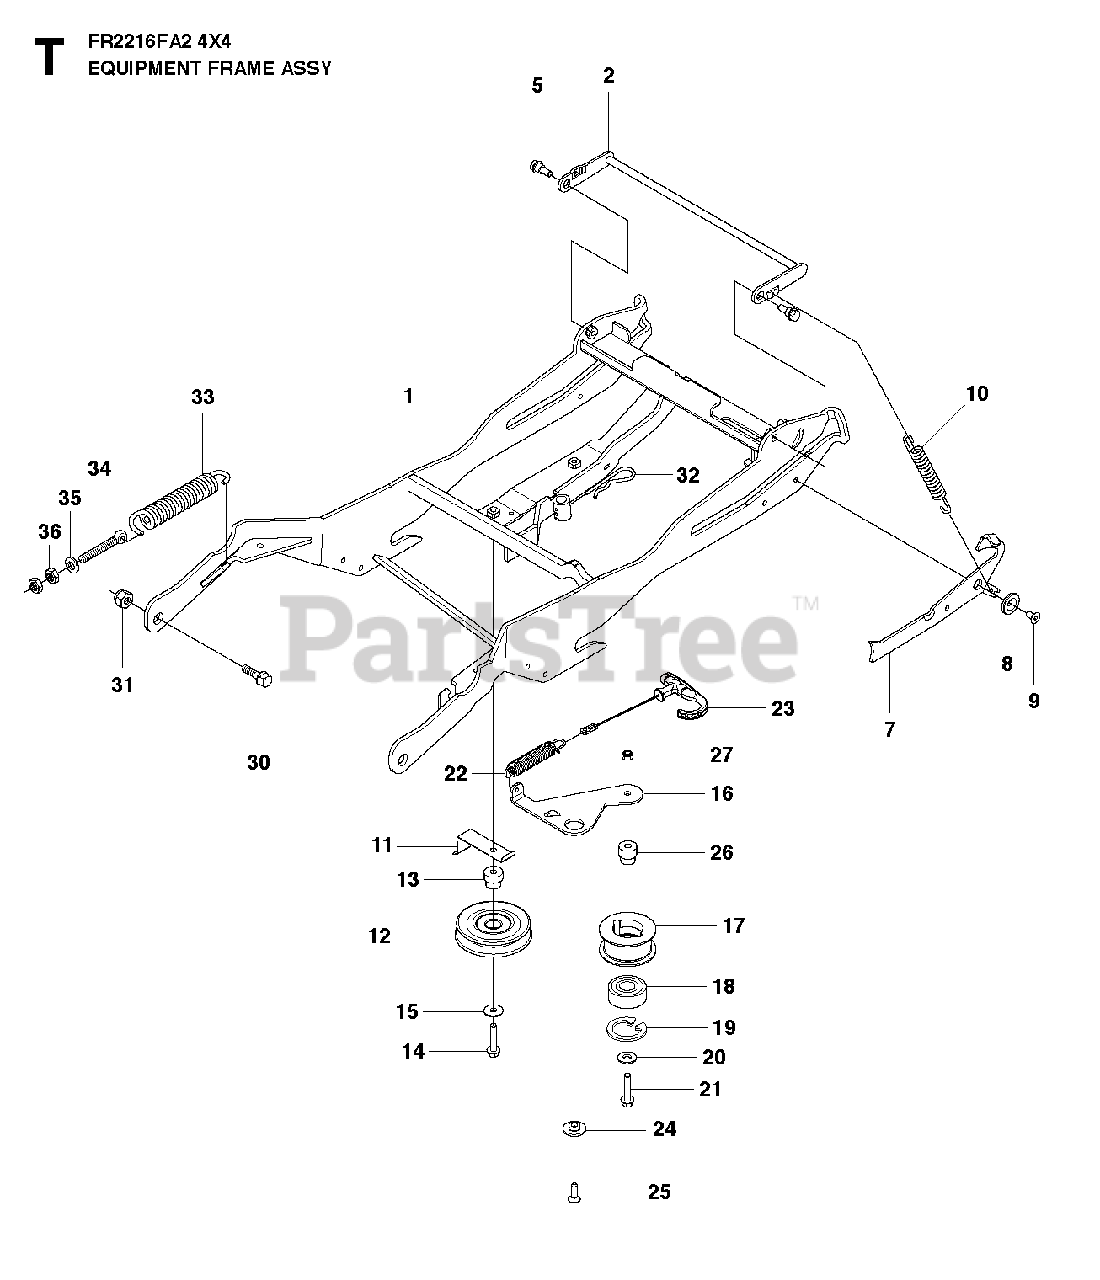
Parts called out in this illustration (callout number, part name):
9	SCREW IHCSFM
11	BELT GUIDE
17	%PULLEY
18	BALL BEARING 6004-2RS1
19	RETAINING RING
23	HANDLE ASSY
24	WASHER
27	LOCKNUT M8
35	WASHER
